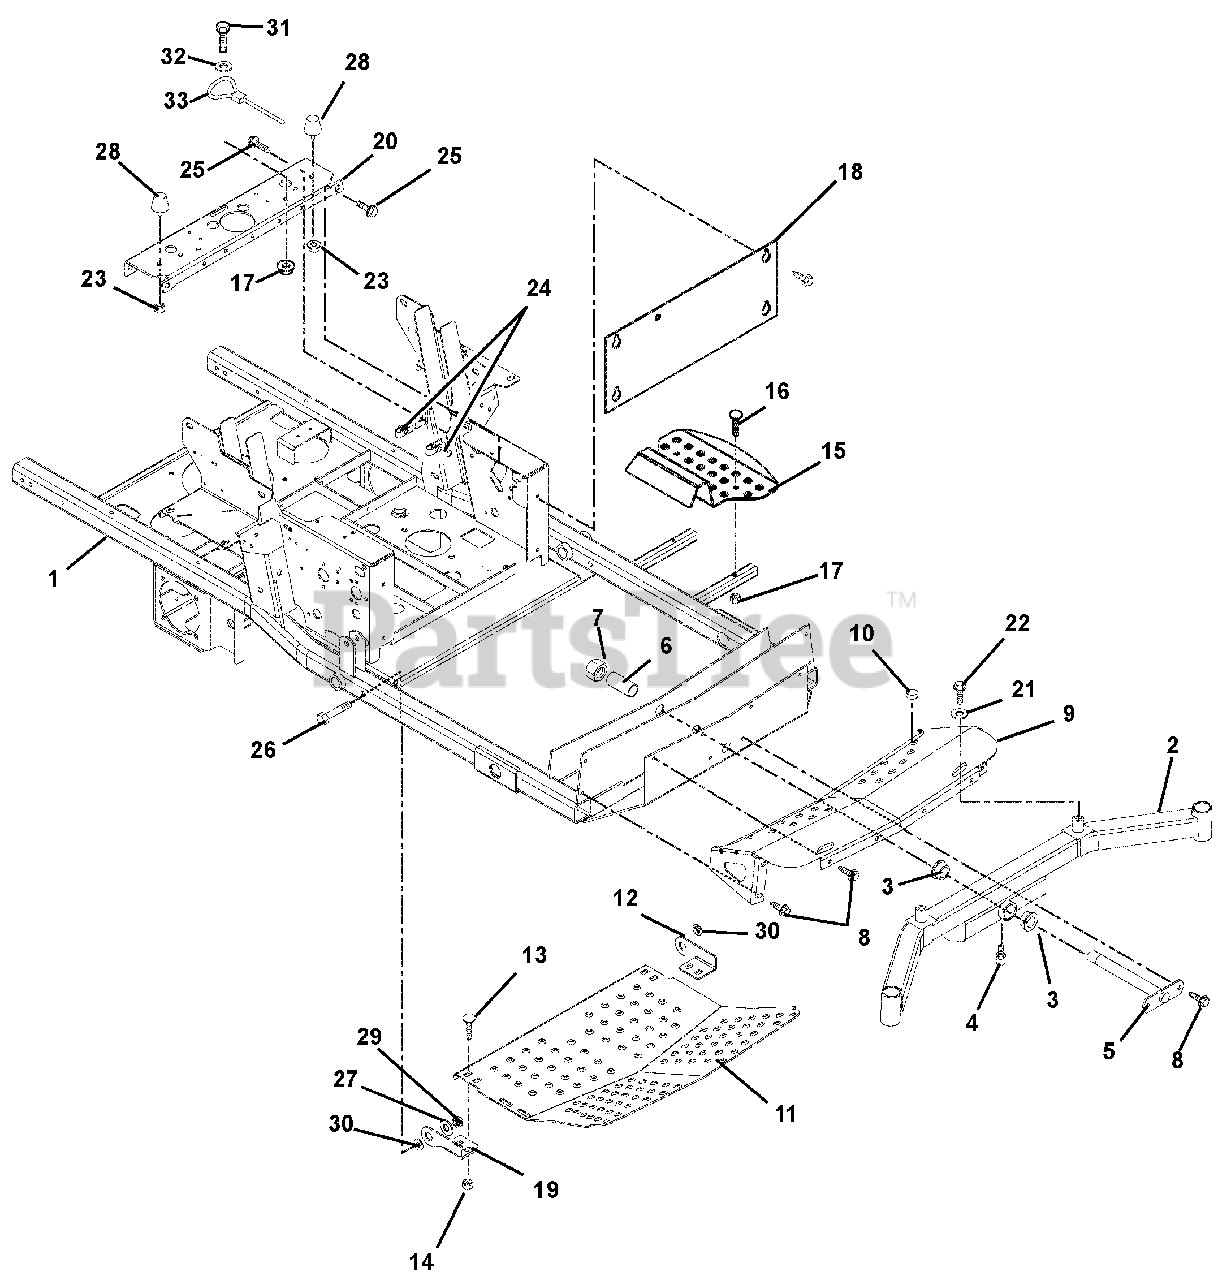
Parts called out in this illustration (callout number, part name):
1	Weldment, Frame
2	Weldment, Axle
3	Bushing, Flange 1.02 x 1.385 x .75 x 1.75
4	Fitting, Lube .25-28 x .256
5	Pin, Axle
7	Nut, Locking Nylon 1.00-14
8	Screw, Tapping .38-16 x .75
9	Weldment, Axle Cover
10	Button, Bumper
11	Panel, Inspection
12	Hinge, Footboard Left Hand
13	Bolt, Round Head Square Neck .38-16 x 1.00 Grade 5
14	Nut-Locking-Top-Flange .38-16
15	Step, Ingress
16	Bolt, Round Head Square Neck .31-18 x 1.75 Grade 5
17	Nut, Locking Top Flange .31-18
18	Plate, Kick
19	Hinge, Footboard Right Hand
20	Channel, Cross
21	Washer, Flat Steel .640 x 1.81 x .25
22	Bolt, Hex .50-20 x 1.00 Grade 5
23	Nut, Locking Flange .312-24
24	Nut, Retainer .375-16 x .37
25	Bolt, Serrated Hex Flange Washer Head .38-16 x 1.00
26	Bolt, Hex .50-13 x 3.25 Grade 5
27	Washer, Flat Steel .563 x 1.38 x .109
29	Nut-Locking-Top-Flange .50-13
30	Bushing, Flange .515 x .75 x .275 x 1.12
31	Bolt, Hex .31-18 x .75 Grade 5
32	Washer, Flat Steel .328 x 1.00 x .094
33	Cable, Seat Prop.
